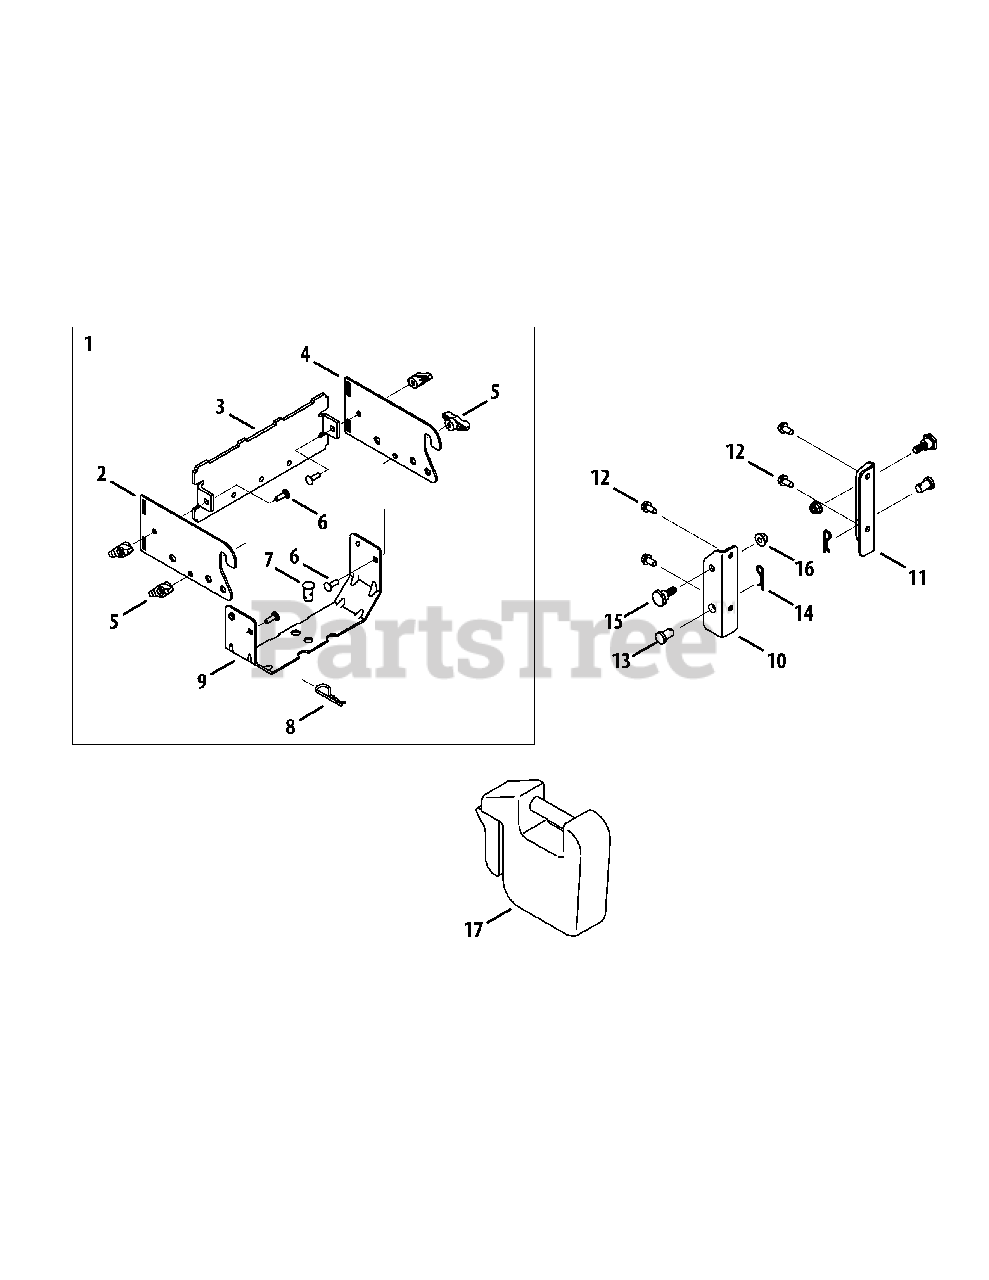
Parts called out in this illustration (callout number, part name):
1	Mounting Bracket Kit (Incl. Ref. 2-4)
2	Hitch Bracket, RH
3	Rear Attachment Bracket
4	Hitch Bracket, LH
6	Carriage Screw, 5/16-18 x 1.00"
7	Clevis Pin, .62" Dia.
8	Internal Cotter Pin, .148 x 3.00
9	Universal Bracket Support
10	Mounting Bracket, RH
11	Mounting Bracket, LH
12	Tap Screw, 5/16-18 x .750
13	Clevis Pin, .50 x .78 Lg.
14	Click Pin, .092 x 1.64 Lg.
15	Shoulder Screw, .625 x .412
16	Flange Lock Nut, 3/8-16
17	Suitcase Weight, 45 lb.
